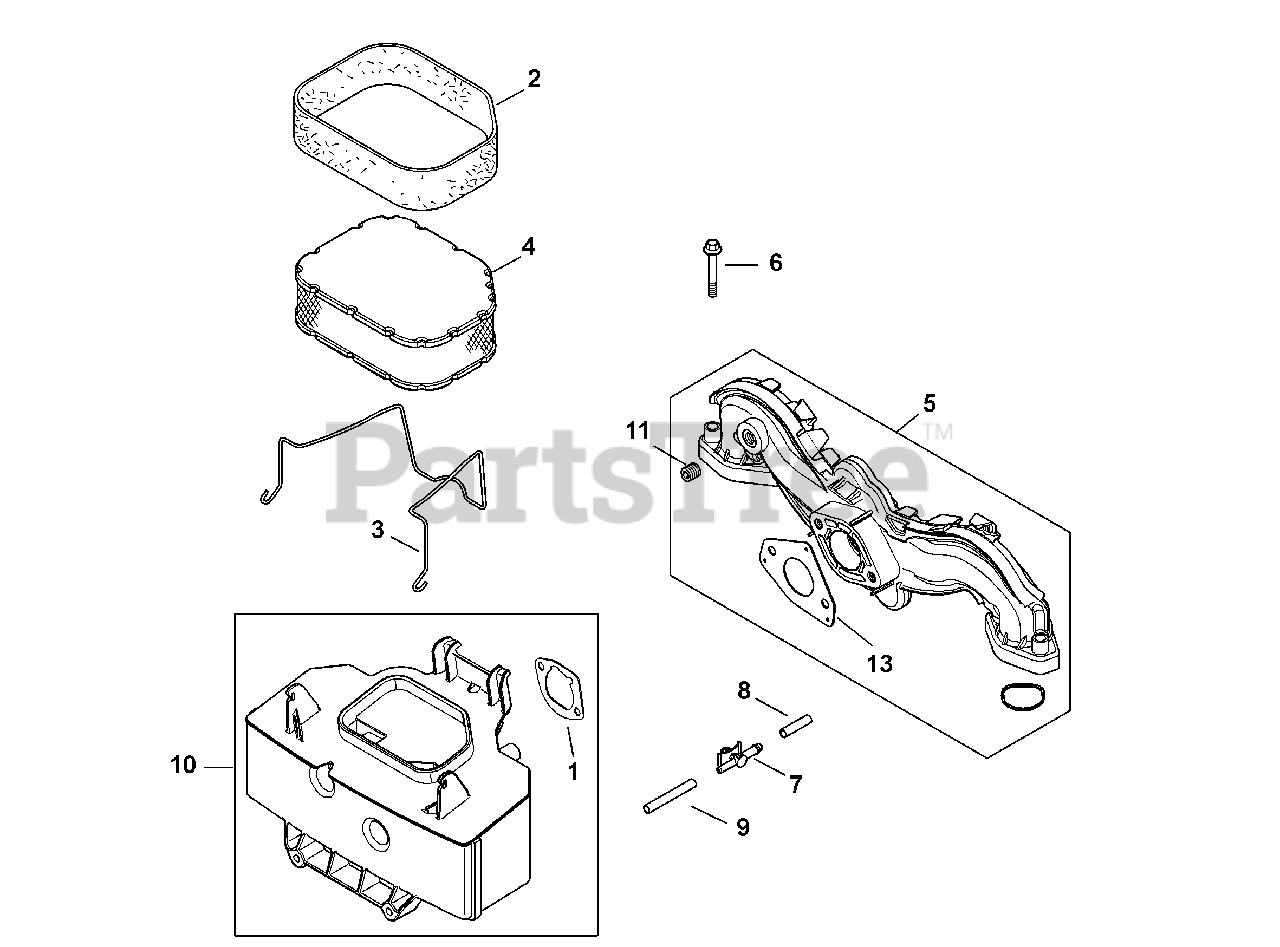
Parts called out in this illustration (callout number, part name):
1	Air Cleaner Base Gasket
2	Pre-Cleaner Element
3	Air Cleaner Element Latch
4	Air Filter Element
5	Intake Manifold Kit
5	Intake Port O-Ring
6	Flange Screw, M6 x 1.0 x 40
7	Evaporative Connector
8	Evaporative Mask
9	Evaporative Hose, 20"
10	Air Cleaner Base
11	Pipe Plug, 1/8
13	Carburetor Gasket
